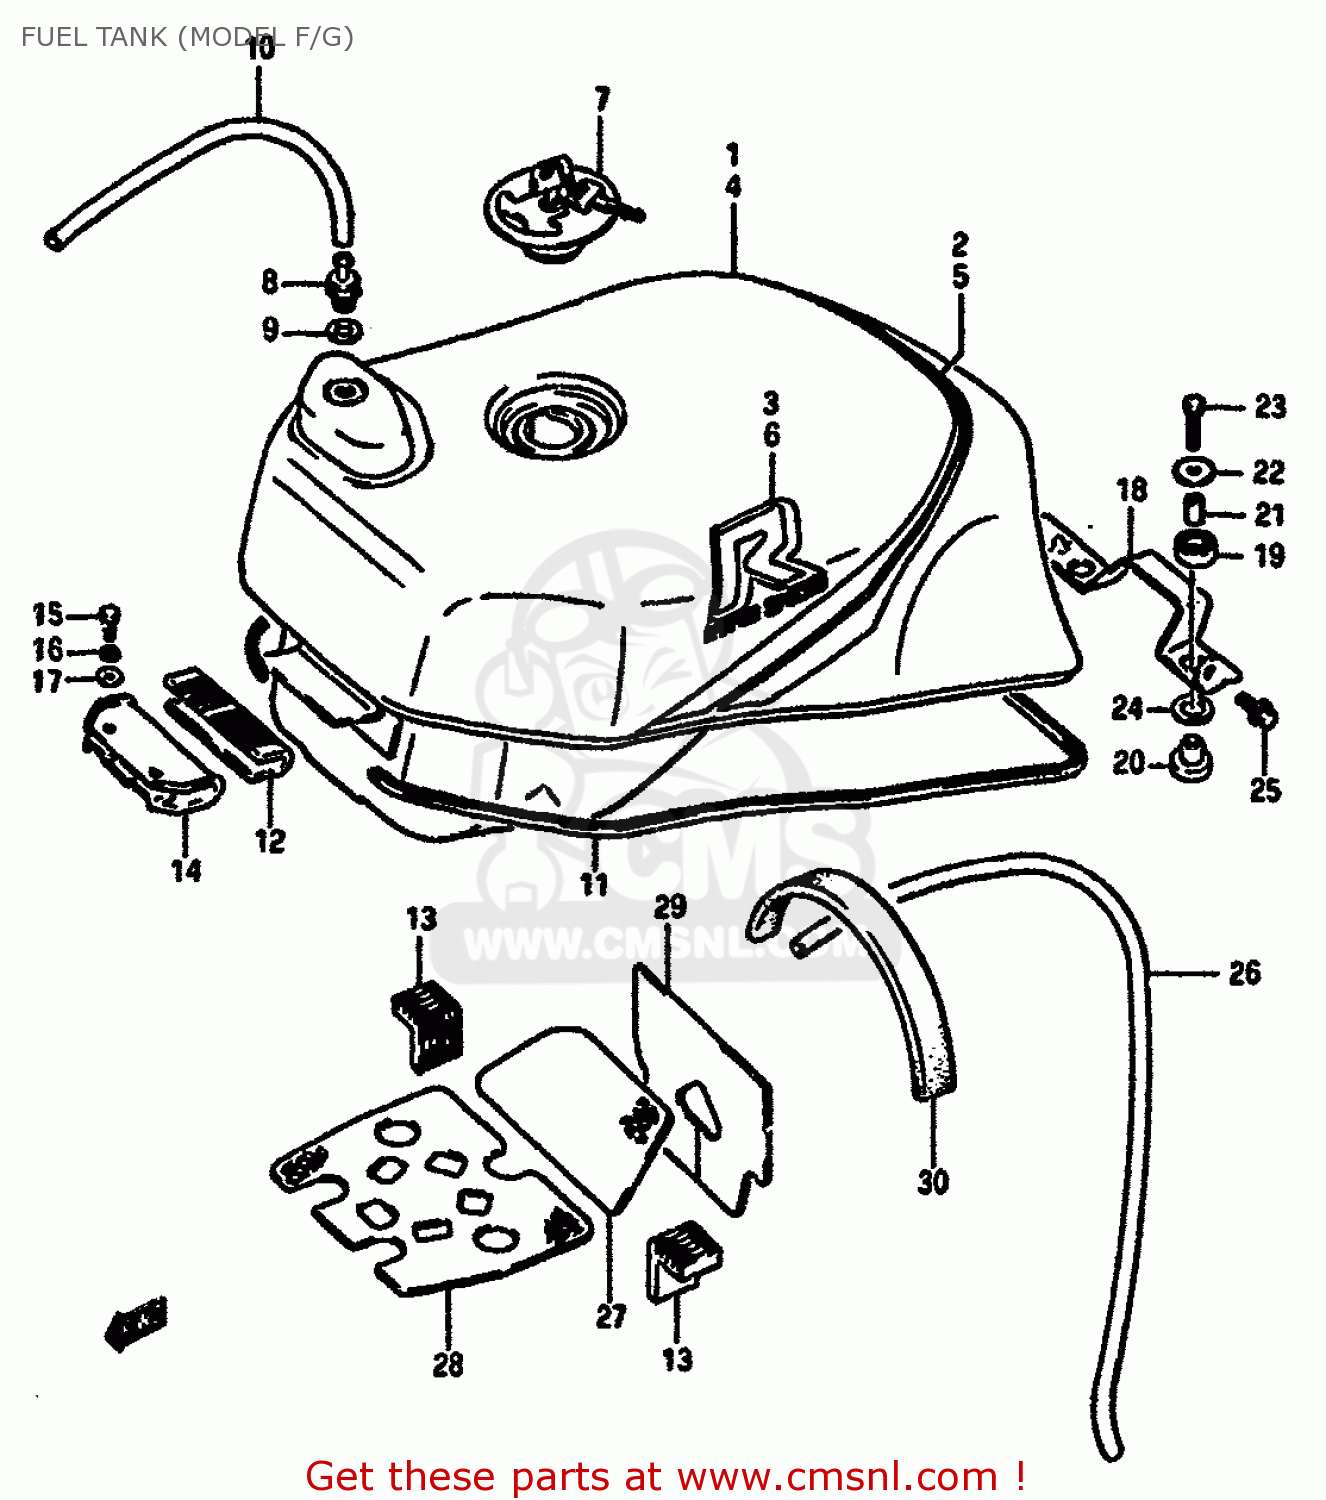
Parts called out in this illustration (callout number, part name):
1	TANK ASSY,FUEL
2	TAPE SET,FUEL TANK
3	EMBLEM
4	TANK ASSY,FUEL
5	TAPE SET,FUEL TANK
6	EMBLEM
7	CAP SET,FUEL TANK
8	PLUG, FUEL TANK BREATHER
9	GASKET(12.5X20X2.5) (NAS)
10	HOSE,FUEL
11	MOLDING,FUEL TANK
12	CUSHION,FUEL TANK,FRONT
13	CUSHION,FUEL TANK
14	BRACKET,FUEL TANK FR
15	BOLT
16	WASHER,LOCK
17	WASHER
18	BRACKET,SEAT SUPPORT,FRONT
19	CUSHION
20	CUSHION
21	SPACER
22	WASHER (6.5X24X1.6)
23	BOLT ,6X35
24	WASHER (12.5X24X1.6)
25	SCREW(6X16)
26	HOSE,FUEL
27	SHIELD,FUEL TANK HEAT
28	SHIELD,FUEL TANK HEAT
29	HEAT SHIELD,FUEL TANK
30	SHIELD,TANK & CLEANER
